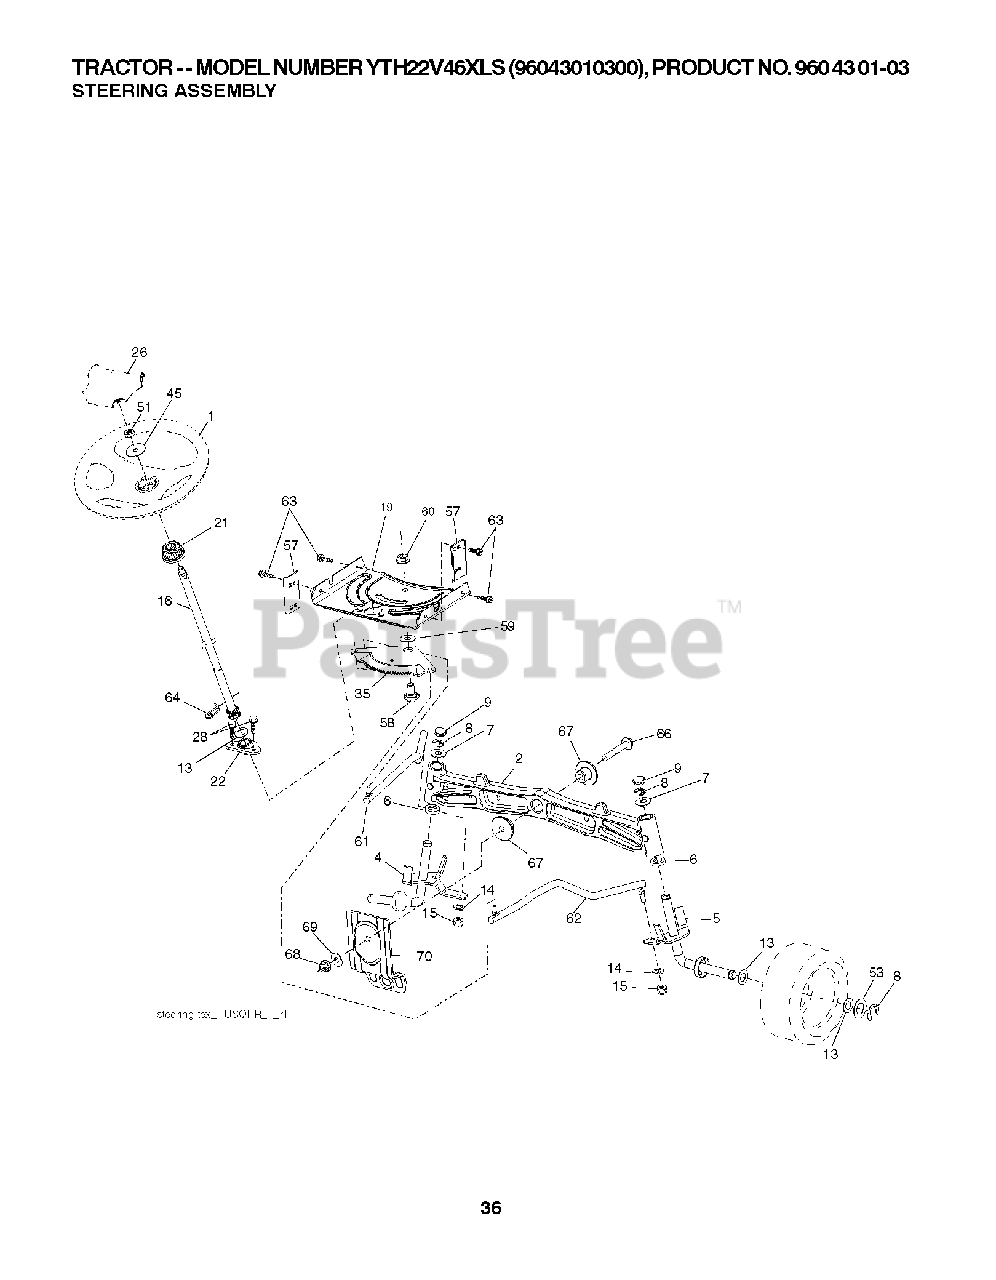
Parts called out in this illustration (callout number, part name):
1	WHEEL.STEER.HUSQ.SR.498.OVMLD
2	AXLE.CAST.IRON
4	SPINDLE.WELDED.LH.15"TEX
5	SPINDLE.WELDED.RH.15"T
6	THRUST WASHER
9	CAP.SPINDLE.BLACK
14	WASHER, LOCK 3/8
15	NUT CROWNLOCK 3/8-24
16	SHAFT, STEERING
19	PLATE.STEER.DDL.NLT/NG
21	ADAPTER, WHEEL STNG..
22	STEERING.SUPT.LOWER.
26	INSERT.CAP.WHL.STRG.HUSQ.PREM
28	SCREW, 3/8-16X3/4
35	GEAR.SECTOR.PLATE.DDL.
45	WASHER 9/16"ID, 2 3/8"OD
51	NUT.HEX.1/2-20
53	WASHER.HARDENED
57	BRACKET.UPSTOP.TEX
58	BOLT.SHOULDER.SECTOR.P
59	WASHER.THURST.SECTOR.S
60	NUT FLANGE LOCK 5/8-11
61	DRAGLINK.LH.BALLSTUD.D
62	DRAGLINK.RH.BALLSTUD.D
63	SCREW
64	RETAINER.CLIP.SPRING.S
66	BOLT HEX FGHD 7/16-14 X 3 SERR
67	BUSHING.PM.FRONT AXLE
68	NUT.LOCK.FLANGE.7/16
69	WASHER.1.5X.505X.118
70	BRKT.DECK.SUSPENSION.F
